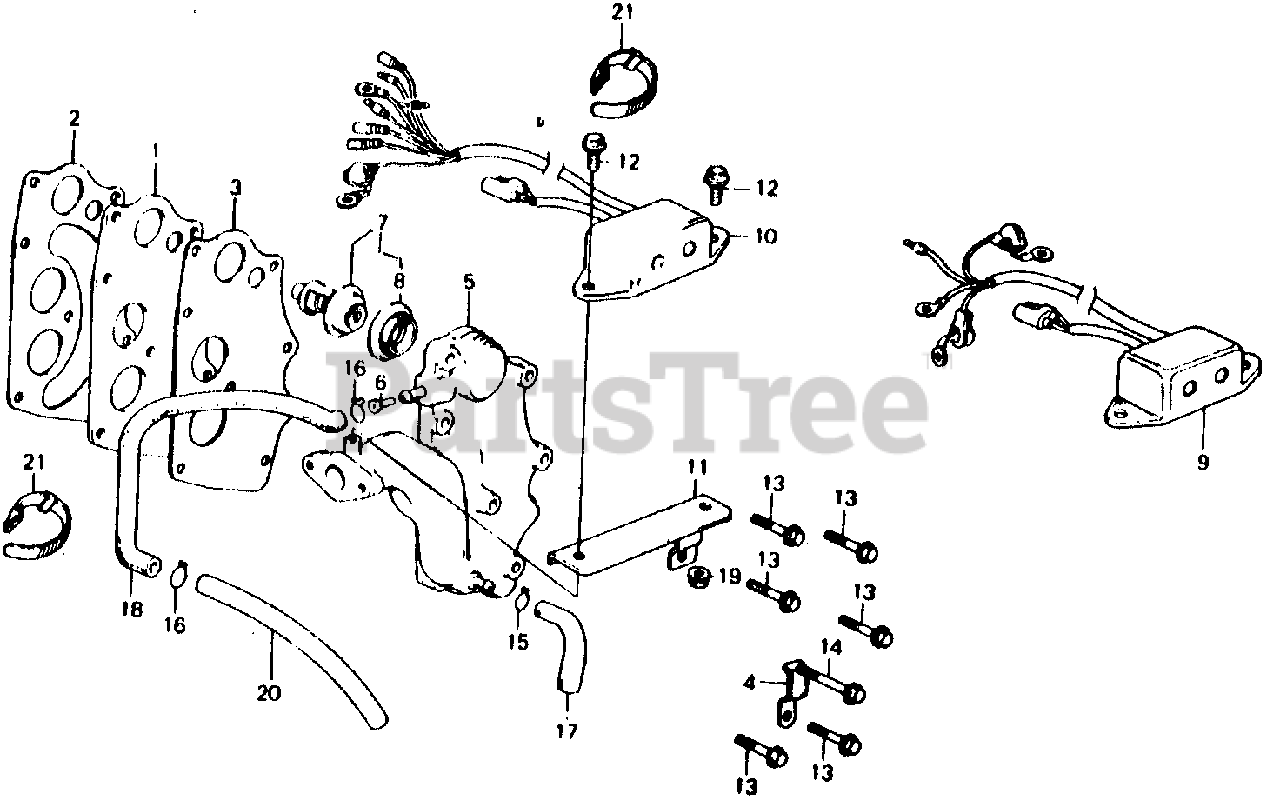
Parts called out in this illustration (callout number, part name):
1	PLATE, EX. CHAMBER
2	GASKET, EX. CHAMBER
3	GASKET, EX. CHAMBER
4	CLAMP, FUEL TUBE (NOT AVAILABLE)
5	MANIFOLD, IN. *NH8* (DARK GRAY)
6	NOZZLE, THROTTLE
7	THERMOSTAT ASSY.
8	RUBBER, THERMOSTAT
10	MODULE, IGNITION CONTROL (CDI) (NOT AVAILABLE)
11	STAY, IGNITION CONTROL MODULE
11	STAY, IGNITION CONTROL MODULE (CDI)
12	BOLT, FLANGE (6X12)
13	BOLT, FLANGE (6X28)
14	BOLT, FLANGE (6X40) (NOT AVAILABLE)
15	CLIP, TUBE (B8)
16	CLIP, TUBE (B12)
17	TUBE, WATER CHECK (NOT AVAILABLE)
18	TUBE, BYPASS
19	NUT, HEX. (6MM)
21	BAND B1, WIRE
